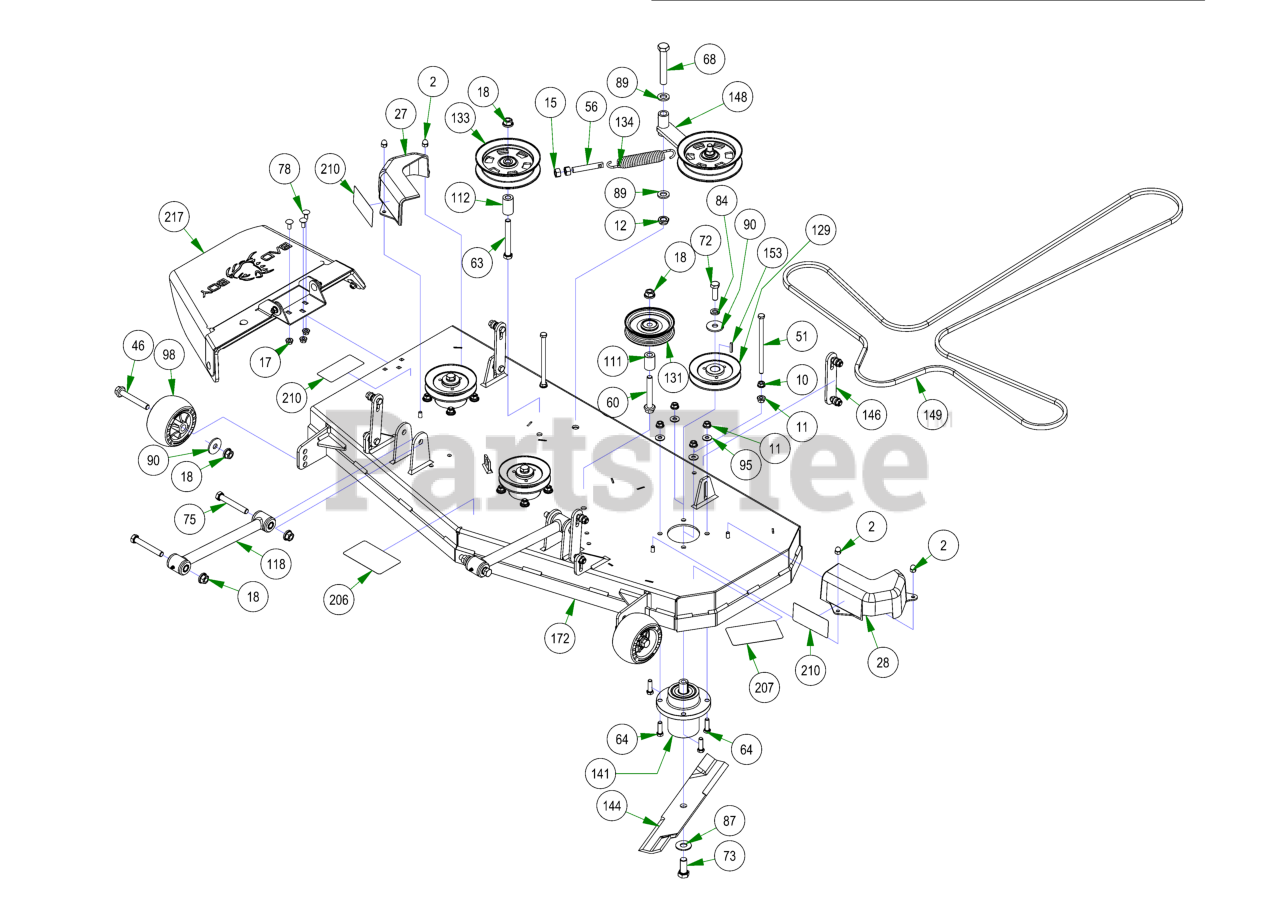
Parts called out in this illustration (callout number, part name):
2	5/16-18 ACORN NUT HIGH-CROWN ZC
10	3/8-16 HEX SERRATED FLANGE NUT HARD/ZINC
11	3/8-16 NYLON INSERT FLANGE LOCKNUT (GR.F) ZINC
12	5/8-11 NYLON INSERT JAM LOCKNUT ZINC
15	1/2-13 HEX NUT ZINC
17	5/16-18 NYLON INSERT FLANGE LOCKNUT ZINC
18	1/2-13 NYLON INSERT FLANGE LOCKNUT ZINC
27	pulley cover chute side
28	pulley cover non-chute side
46	1/2-13 X 90MM HEX FLANGE BOLT W/SHOULDER (GR.8) ZINC
51	3/8-16 X 6.5 HEX CAP SCREW (GR.5) ZINC
56	All Thread
60	1/2-13 X 3-1/2 HEX FLANGE BOLT (GR.8) ZINC
63	1/2-13 X 4 HEX CAP SCREW (GR.8) ZINC YELLOW
64	3/8-16 X 1-1/4 HEX CAP SCREW (GR.5) ZINC
68	5/8-11 X 4 HEX CAP SCREW (GR.8) ZINC YELLOW
72	1/2-20 X 1-1/2 HEX CAP SCREW (GR.5) ZINC
73	5/8-18 X 1-1/2 HEX CAP SCREW (GR.8) ZINC YELLOW
75	1/2-13 X 3-1/2 HEX CAP SCREW (GR.5) ZINC
78	5/16-18 x 3/4 Carriage Bolt
84	1/2 SPLIT LOCKWASHER (GR.8) ZINC/YELLOW
87	5/8 USS FLAT WASHER (1-3/4" OD) GR.8 ZINC YELLOW
89	.635 ID X 1.120 OD X .140 THICK FLAT WASHER NYLON
90	1/2 BELLEVILLE WASHER (1-5/8 OD X .140 THK) ZINC
95	5/16 USS FLAT WASHER (7/8 OD) ZINC
98	Deck Wheel
111	.502 ID X .750 OD X 1.500 Long Spacer
112	1 3/4" Pulley Spacer
118	Hybrid Turnbuckle/Deck Locator
129	MZ Deck Pulley
131	4 3/4" Idler Pulley
133	5-3/4 Idler Pulley
134	Deck Idler Spring
141	Spindle Assembly-MZ
144	48" High Lift Fusion Blade
146	Deck Hanger Assembly
148	2017 MZ/ZT Deck Idler Assembly
149	B147 Deck Belt
153	3/16 X 1 SQ MACHINERY KEY 1018 STL ZINC
172	2023 48" x 4" Deck
206	2017 MZ Magnum 48"/42" Deck Route Decal
207	2018 48" Deck Decal
210	Danger Decal-Spindle/Discharge
217	MZ Discharge Chute Assembly
